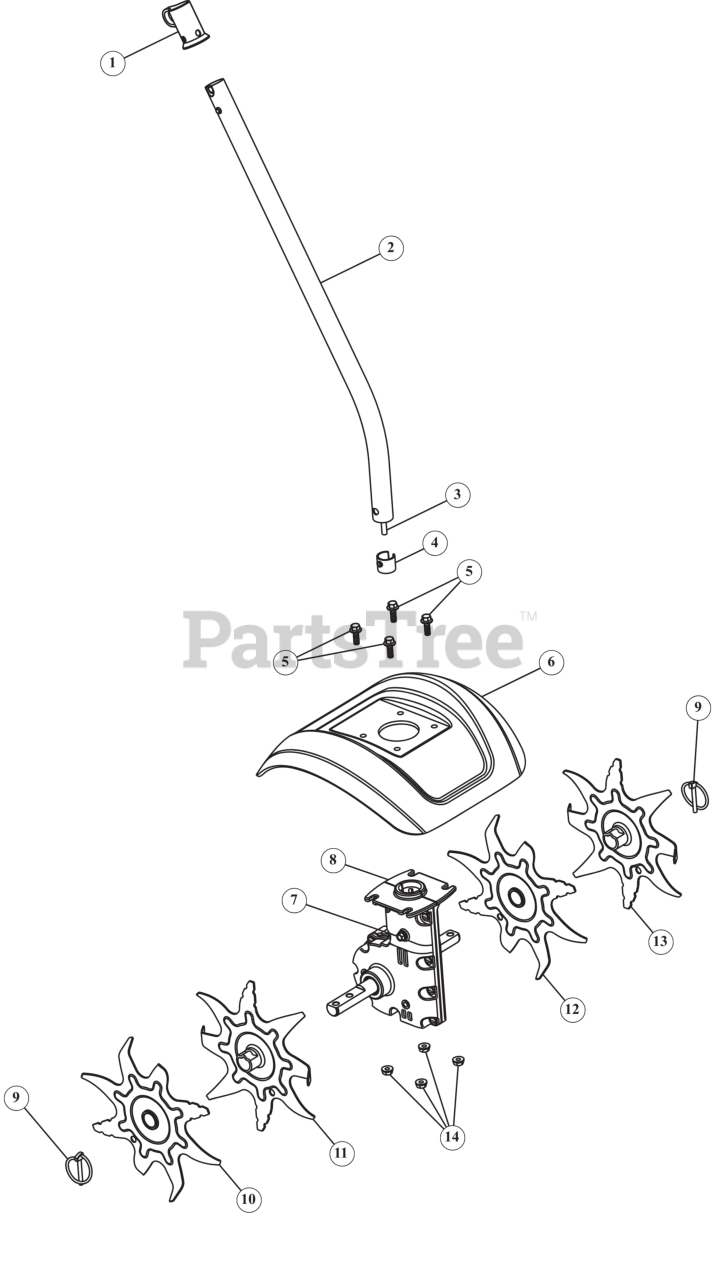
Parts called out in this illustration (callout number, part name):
1	HANGER
2	BOOM 25.4"
3	SHAFT, DRIVE
4	RETAINER SLEEVE
5	HEX SCREW 1/4-20X.
6	TINE SHIELD
7	SCREW 1/4-20 X.500
8	GEARBOX ASSEMBLY CULT
9	LYNCH PIN .1875
10	TINE ASSEMBLY (LH)I (RH)O
11	TINE ASSEMBLY (LH)O (RH)I
12	TINE ASSEMBLY (LH)I (RH)O
13	TINE ASSEMBLY (LH)O (RH)I
14	LOCK NUT 1/4
